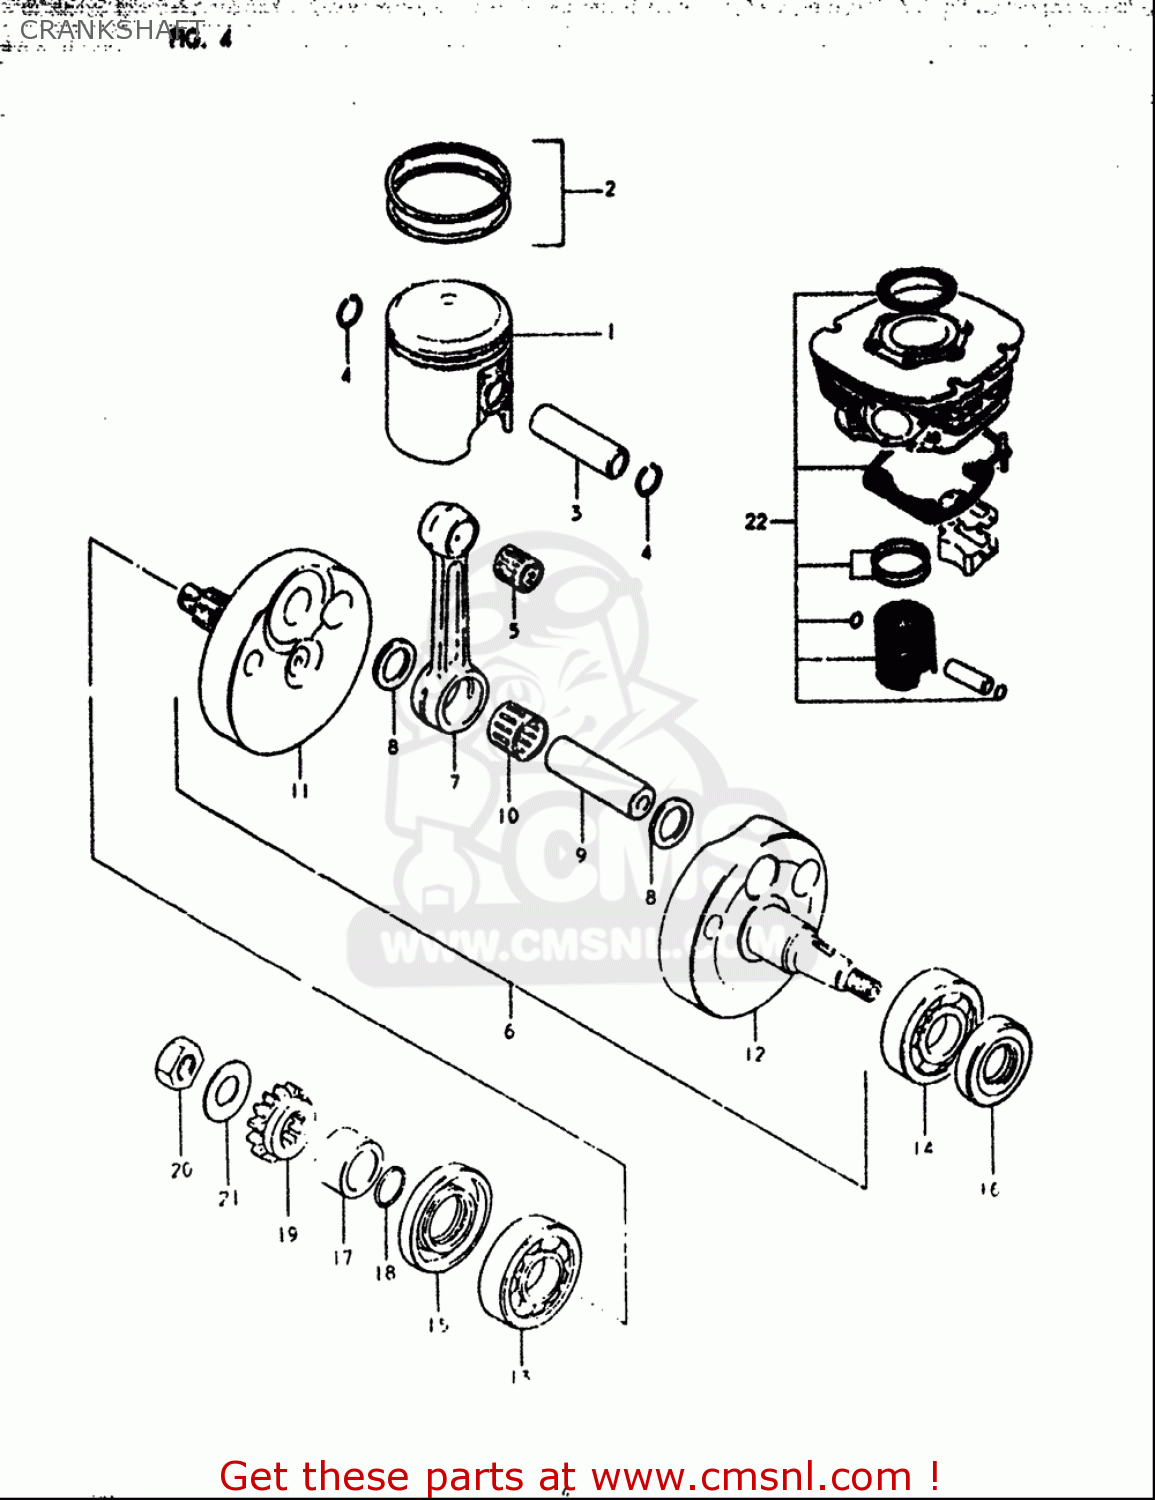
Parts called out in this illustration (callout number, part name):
1	PISTON
2	RING SET,PISTON
3	PIN,PISTON
4	RING,SNAP 14MM
5	BEARING(14X18X19.8)
7	ROD,CONNECTING
8	WASHER(19X32X1)
9	PIN,CRANK
10	BEARING(19X25X16)
13	BEARING(22X56X16)
14	BEARING(25X52X15)
15	SEAL,OIL(29X47X8)
16	SEAL,OIL(25X44X7)
18	O RING(D:2.4,ID:19.8)
19	GEAR,PRIMARY DRIVE
20	NUT
21	WASHER
